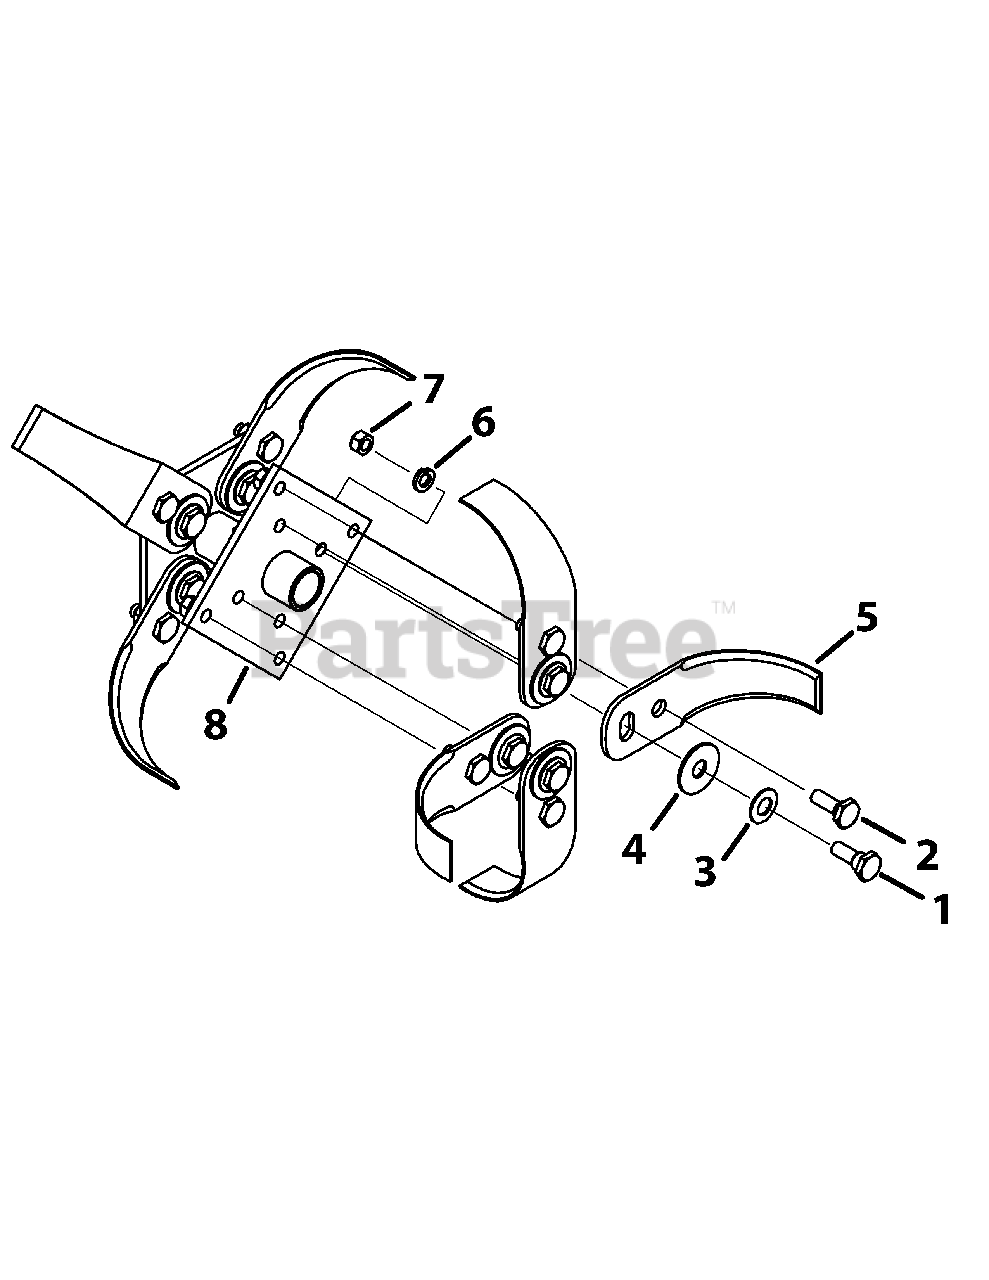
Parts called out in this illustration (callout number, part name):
1	Screw, Shoulder, 3/8-24 x 1/2 x .325
2	Screw, Shoulder, 3/8-24 x 1/2 x .180
3	Washer, Bell, .525 x 1.00 x .050
4	Washer, Flat, .51 x 1.5 x 0.07
5	Articulating Tine
6	Washer, Lock, 3/8
7	Hexlock Nut, 3/8-24
8	Tine Adaptor Assembly
